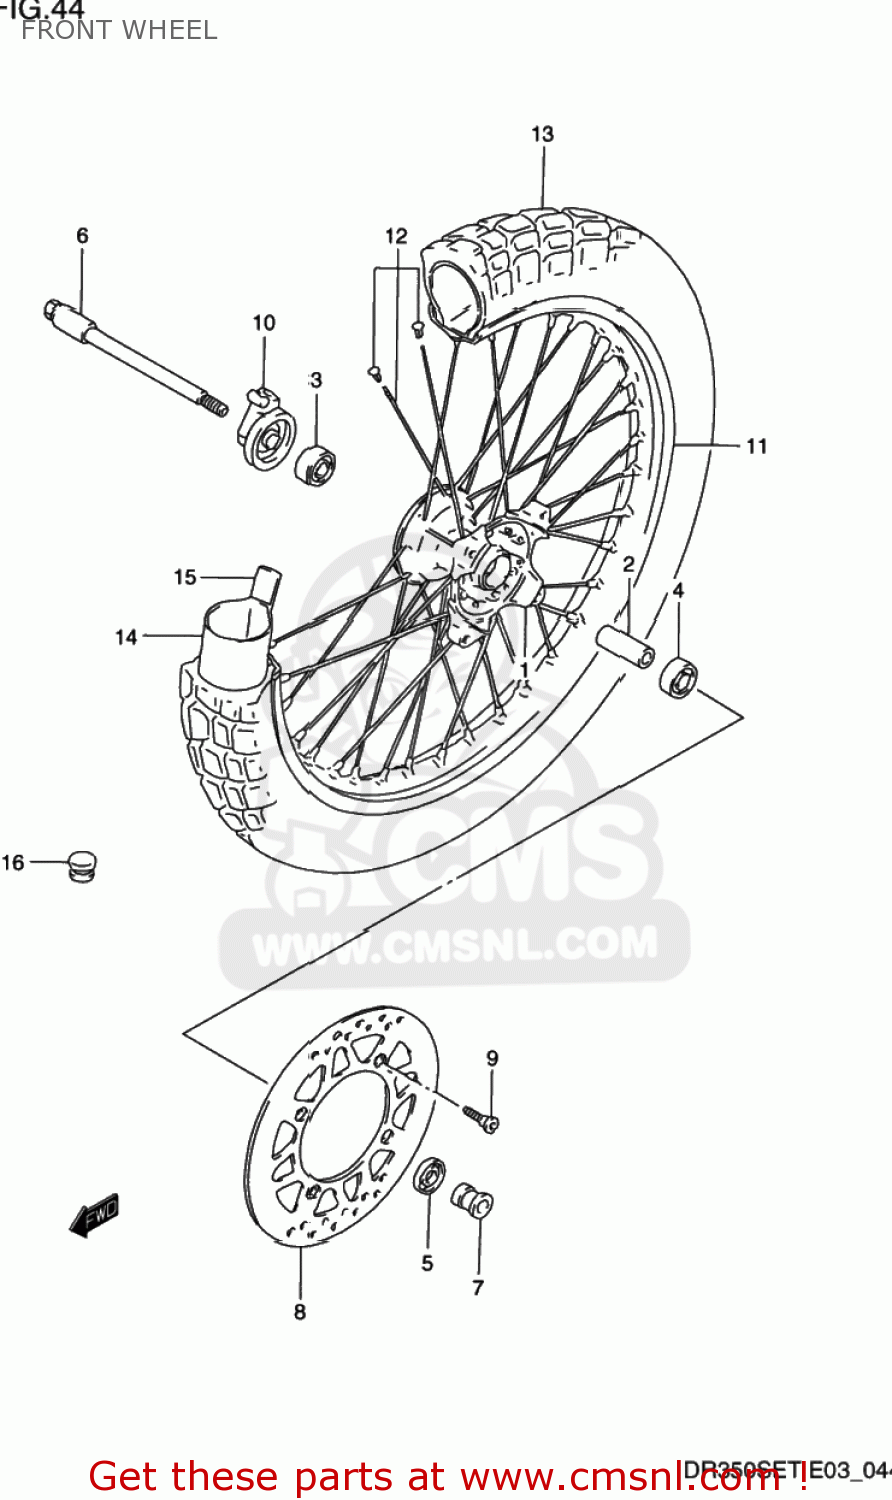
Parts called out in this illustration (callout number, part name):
1	HUB,FR WHEEL
2	SPACER,FR HUB BEARING
3	BEARING
4	BEARING
5	SEAL,OIL(22X35X5)
6	AXLE,FR
7	SPACER,FR AXLE,L
8	DISC,FR BRAKE
9	BOLT,BRAKE DISC
10	BOX ASSY,SPEEDOMETER GEAR
11	RIM,FR WHEEL(1.60X21)
12	SPOKE SET,FR WHEEL
13	TIRE,FRONT
14	TUBE
15	PROTECTOR,WHEEL INNER
16	CAP(OD:12)
